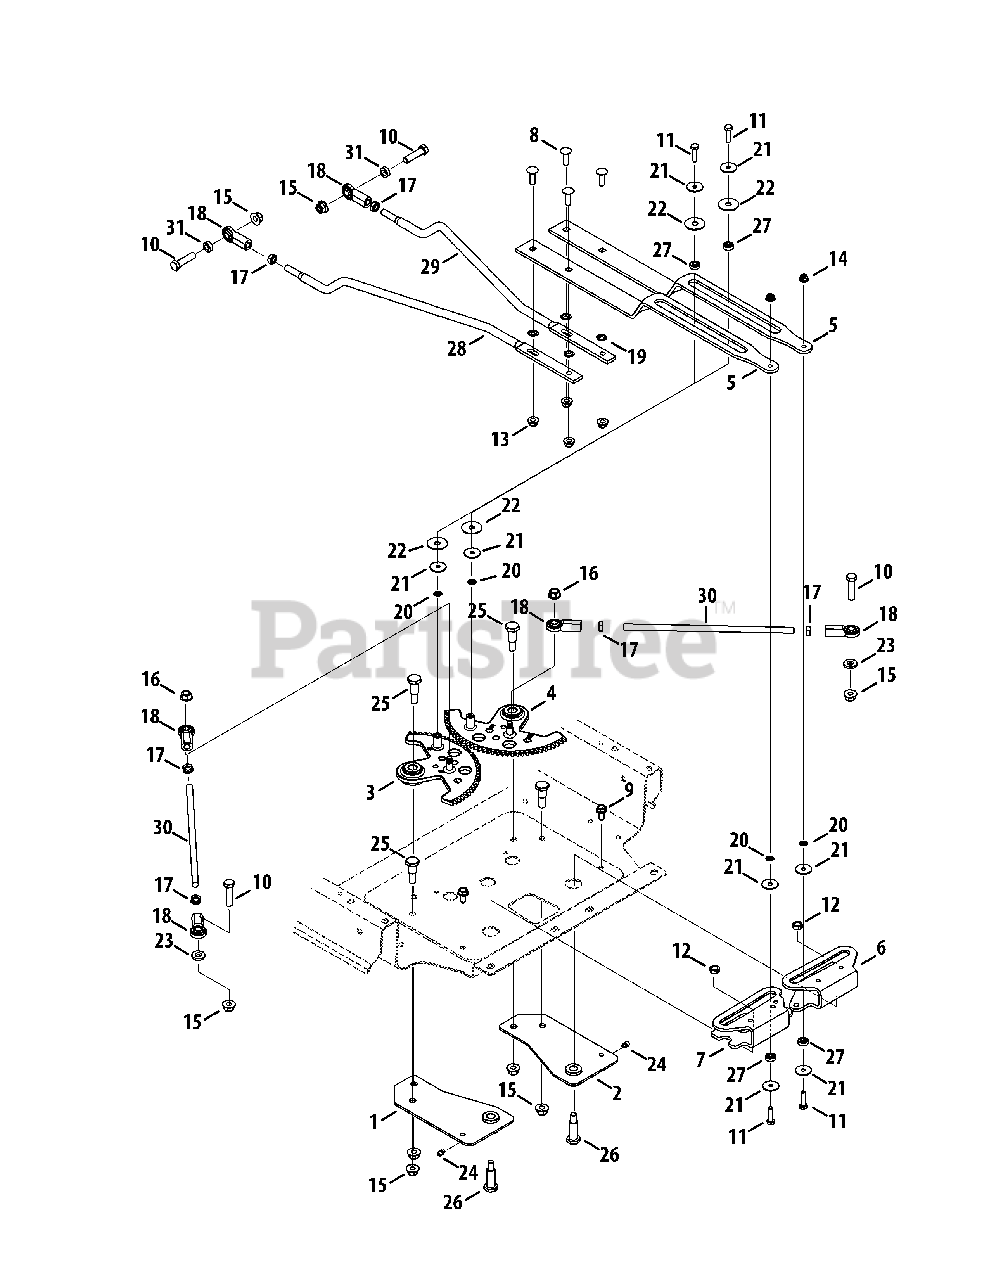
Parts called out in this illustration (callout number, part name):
1	Steering Plate Assembly, RH
2	Steering Plate Assembly, LH
3	Steering Gear Assembly, RH
4	Steering Gear Assembly, LH
5	Control Link
6	Speed Cam Plate, LH
7	Speed Cam Plate, RH
8	Carriage Screw, 5/16-18 x 1.00
9	Hex Washer Screw, 5/16-18 x .750
10	Hex Screw, 3/8-16 x 1.50
11	Hex Screw, 1/4-20 x 1.00
12	Nut, Jamlock, 3/8-16
13	Flange Lock Nut, 5/16-18
14	Flange Lock Nut, 1/4-20
15	Flange Lock Nut, 3/8-16
16	Nut, 5/16-18, Centerlock
17	Jam Nut, 3/8-24
18	Female Ball-Joint
19	Speed Nut, .3125 ID
20	Push Nut, .25 ID x .50 OD
21	Flat Washer, .285 x 1.25 x .060
22	Washer, .355 x 1.25 x .048
23	Flat Washer, .407 x .812 x .135
24	Grease Fitting, 3/16
25	Shoulder Screw, 3/8-16 x .625 x .875
26	Shoulder Screw, .500 x 1.25 x 3/8-16
27	Ball Bearing, .25 x .625
28	Hydro Link, RH
29	Hydro Link, LH
30	Drag Link, .375 Dia.
31	Spacer, .380 ID x .625 OD x .21
